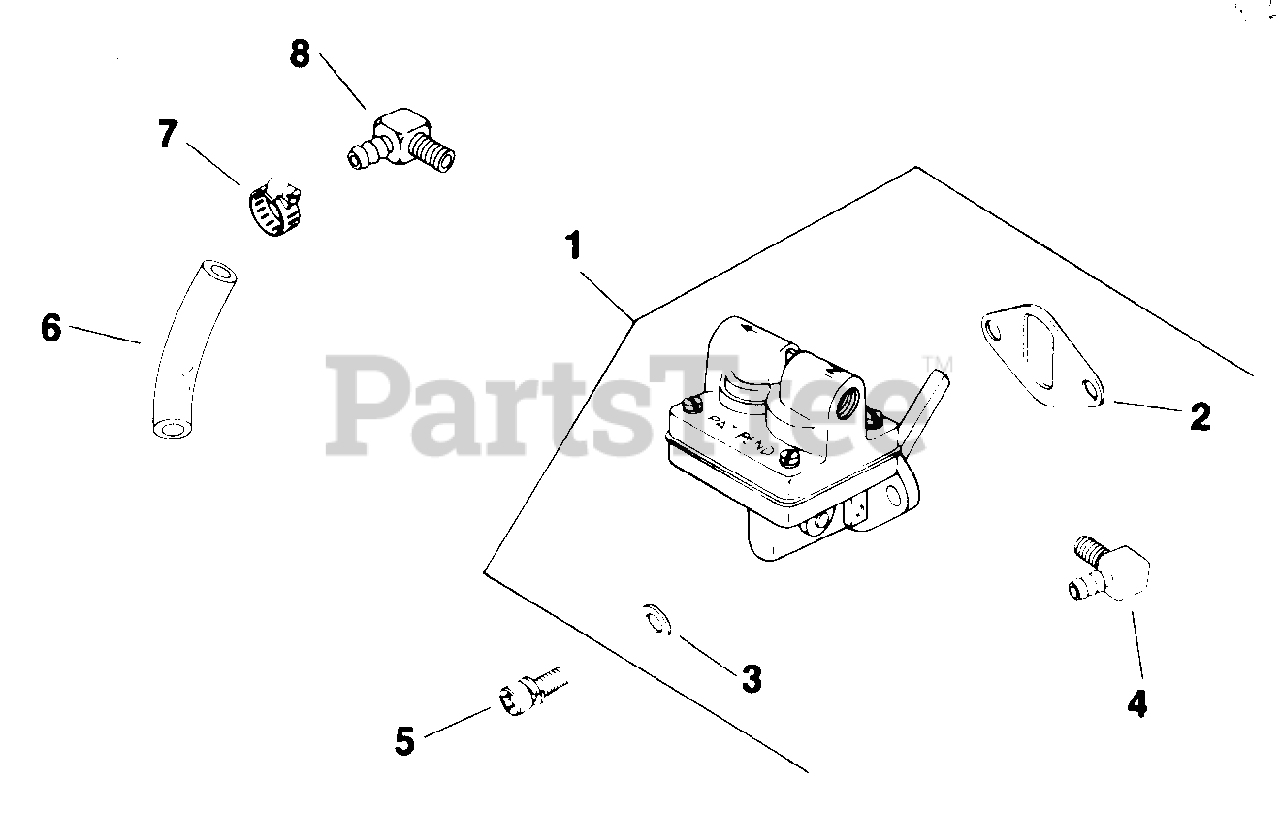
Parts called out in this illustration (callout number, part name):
1	Pump, Fuel Assembly (Includes 2-3)
2	Gasket, Fuel Pump
3	Washer, Plain 1/4
4	Connector, 90ø Hose (For 3/16 I.D. Rubber Hose)
5	Screw, F.H.M. 1/4-20 x 5/8
7	Clamp, Hose
8	Connector, 90ø Hose (For 1/4 I.D. Rubber Hose)
